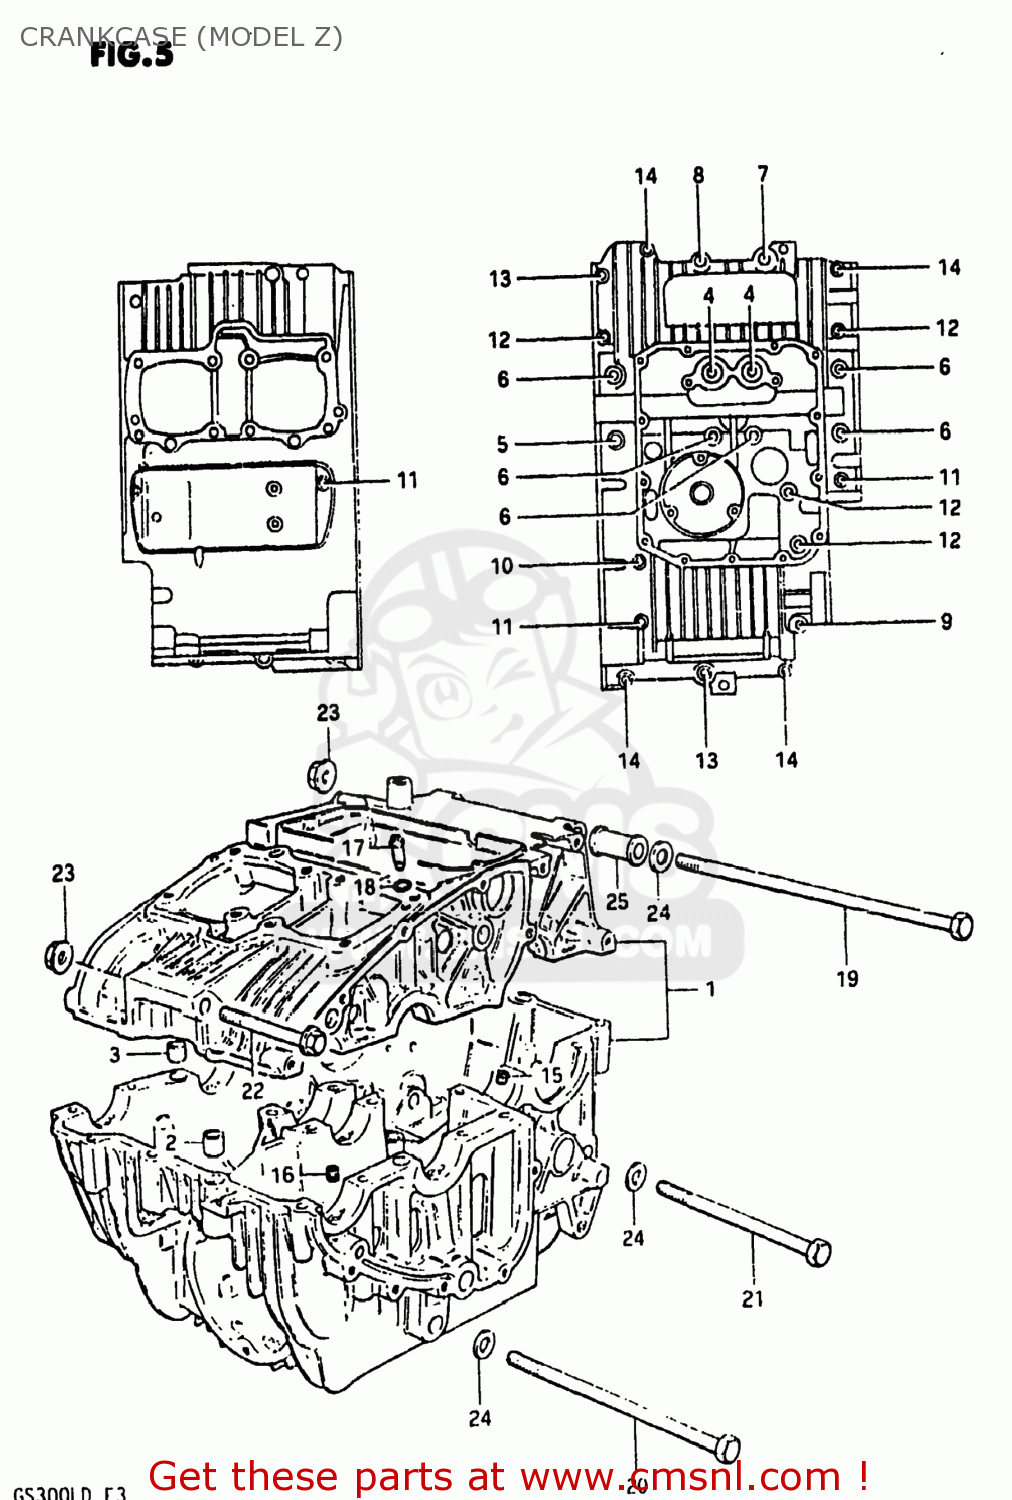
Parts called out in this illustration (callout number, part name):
1	CRANKCASE SET
2	PIN(10.4X13X22)
3	PIN (11X20)(SUS)
4	BOLT
5	BOLT
6	BOLT
7	BOLT 8X65
8	BOLT
9	BOLT (8X40)
10	BOLT(6X125)
11	BOLT
12	BOLT (6X90)
13	BOLT (6X60)
14	BOLT,UNDER
15	JET,AIR(100)
16	JET,AIR
17	JET,AIR
18	O RING(D:1.05,ID:3.1)
19	BOLT
20	BOLT
21	BOLT
22	BOLT (10X90)
23	NUT 10MM
24	WASHER
25	SPACER,ENGINE MOUNT
